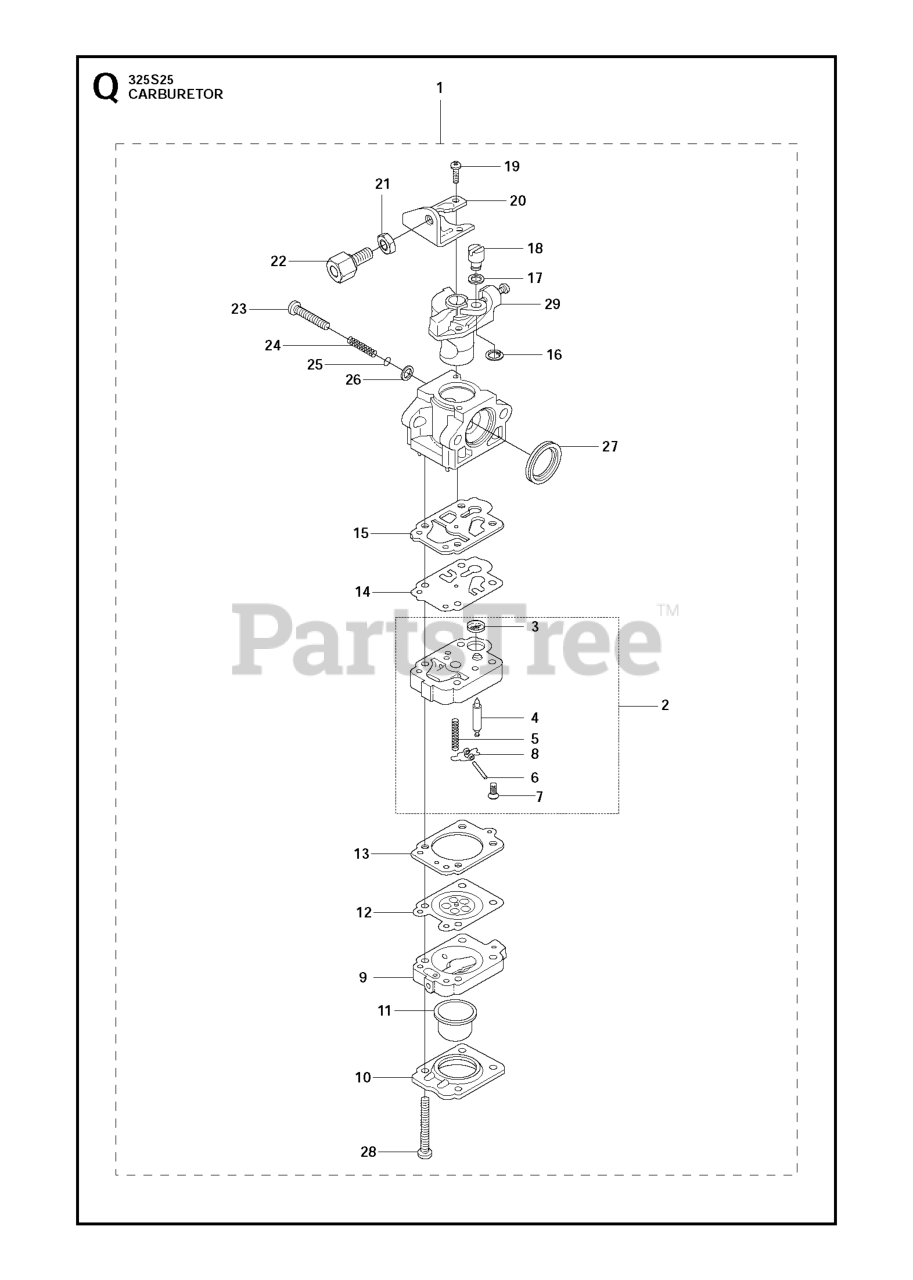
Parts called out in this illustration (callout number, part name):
1	CARBURETOR ASSEMBLY
3	SCREEN
4	VALVE INLET
21	NUT
22	ADJUSTER
24	SPRING
27	RING PACKING
